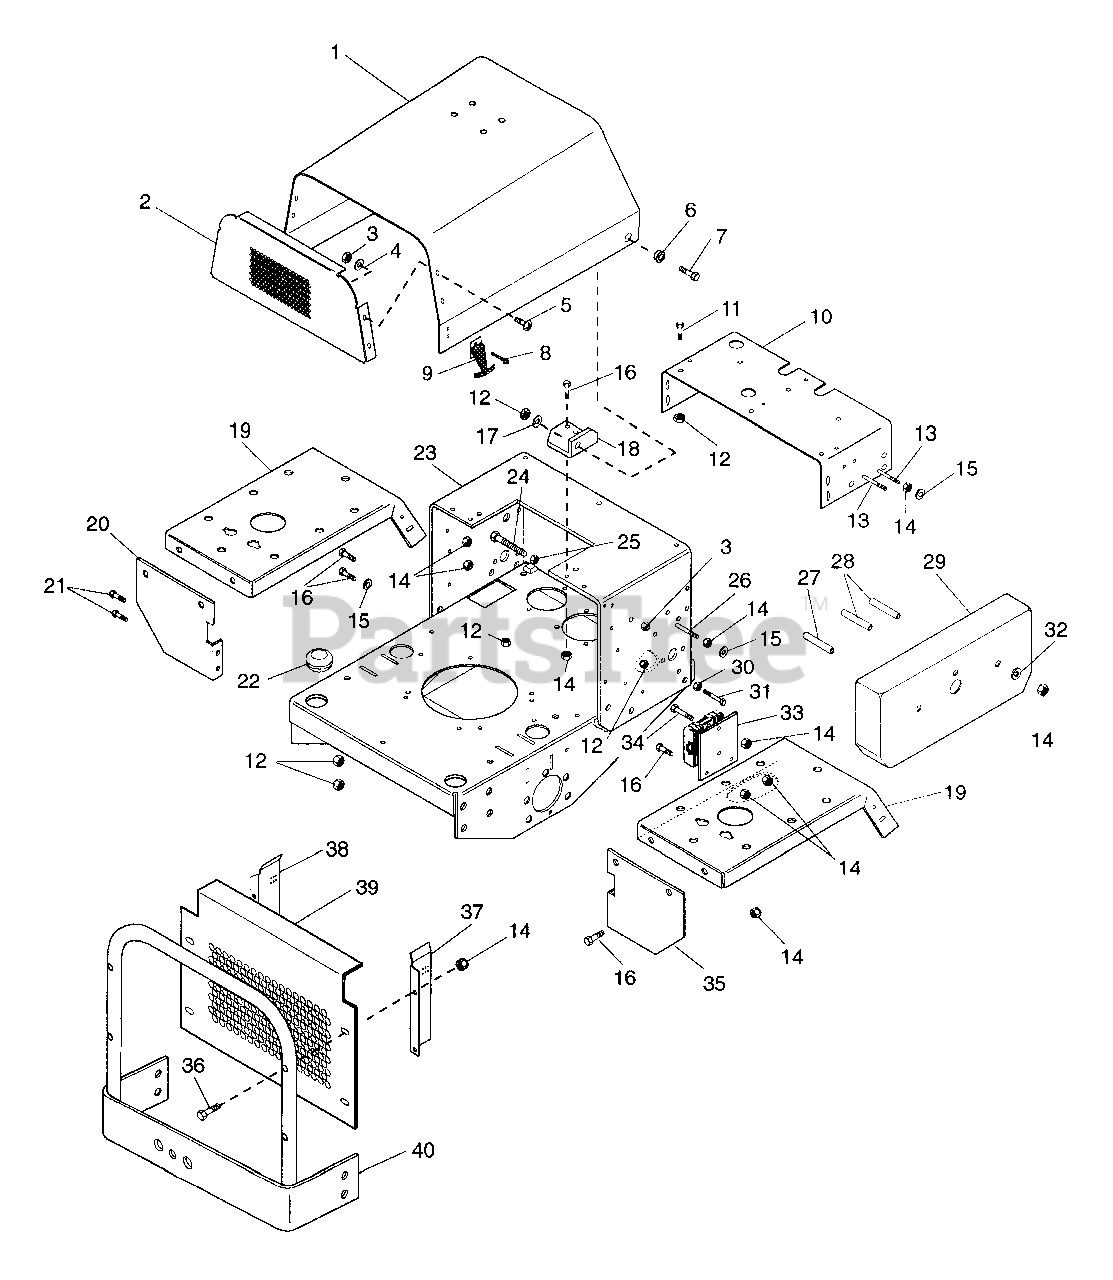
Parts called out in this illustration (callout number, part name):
1	Cover, Engine
2	Grille, Hood
3	Nut-Locking-Nylon .250-20 Grade 2
4	Washer-Flat-Steel .281 x .620 x .065
5	Screw-Machine .25-20
6	Bushing-Flange .406 x .88 x .270 x .140
7	Bolt-Hex .38-16 x 1.00 Grade 5
8	Rivet .125 x .245
9	Latch, Flexible
10	Panel, Silkscreen
11	Bolt-Hex .38-16 x 1.00 Grade 5
12	Nut-Locking-Nylon .375-16 Grade 2
13	Bolt-Hex .31-18 x 4.00 Grade 5
14	Nut-Locking-Nylon .312-18 Grade 2
15	Washer-Flat-Steel .344 x .688 x .065
16	Bolt-Hex .31-18 x .75 Grade 5
17	Washer-Flat-Steel .406 x .812 x .065
18	Bracket, Hood Mounting R.H.
18	Bracket, Hood Mounting L.H.
19	Fender PM2OO
20	Support, Fender L.H.
21	Bolt-Hex .38-16 x 1.25 Grade 5
22	Grommet
23	Weldment, Frame PM2OO
24	Bolt-Hex .25-20 x 3.00
25	Nut .250-20
26	Bolt-Hex .31-18 x 3.75 Grade 2
27	Spacer, Split-Rolled
28	Spacer, Split-Rolled
29	Guard, Linkage
30	Nut-Hex .375-16 Grade 2
31	Bolt-Hex .38-16 x 3.00
32	Washer-Flat-Steel .313 x .875 x .065
33	Plate, Regulator Rectifier Mounting
34	Bolt-Hex .31-18 x 1.25 Grade 5
35	Support, Fender R.H.
36	Bolt-Hex .31-18 x 1,50 Grade 5
37	Bracket, Hood Latch R.H.
38	Bracket, Hood Latch L.H.
39	Bracket, Hood Support
40	Weldment, Rear Guard
